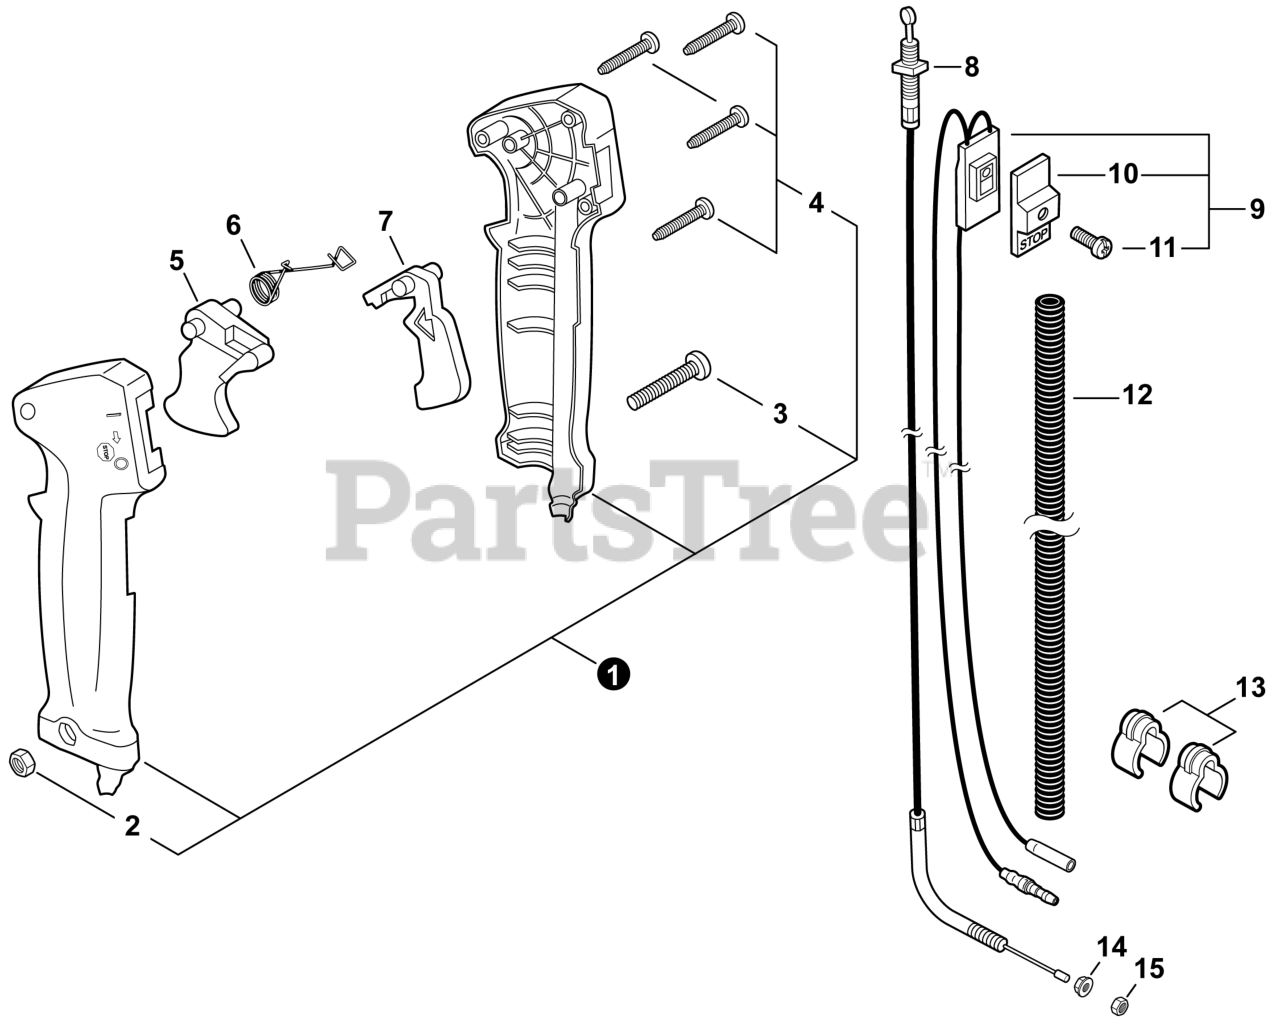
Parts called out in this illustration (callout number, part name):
1	CONTROL HANDLE KIT
3	SCREW 5×30
4	SCREW 3×25
5	TRIGGER, THROTTLE
6	SPRING, TORSION
7	LOCKOUT, THROTTLE
8	CABLE, THROTTLE
9	SWITCH, ON-OFF
10	KNOB, SWITCH - ORANGE
11	SCREW 3×10
12	TUBE, FLEXIBLE 7×790
13	CLIP, CABLE 25 MM
14	NUT, FLANGE M6
